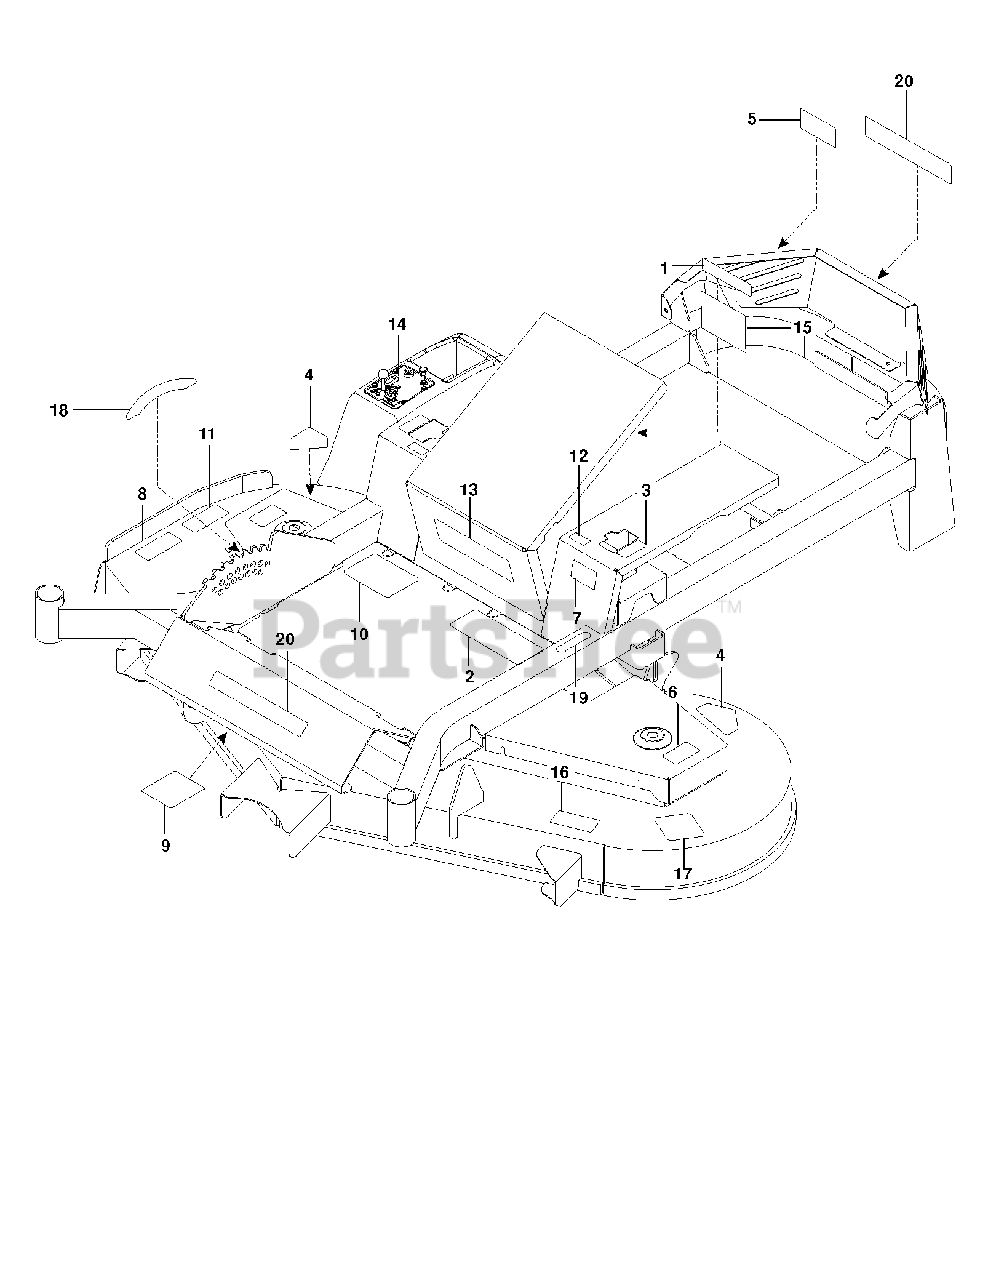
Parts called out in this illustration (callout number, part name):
2	DECAL, WARNING
3	DECAL, MOTION CONTROL
4	DECAL, CPSC
5	DECAL, BELT DRIVE
7	DECAL, FLAG
8	DECAL, EURO SEVERING
9	DECAL, BELT ROUTING
10	DECAL, WARNING
12	DECAL, TRACKING
13	DECAL, RAM ULTRA
15	DECAL, SERVICE
16	DECAL, TRI-FORCE
18	DECAL, HEIGHT ADJUSTMENT
19	DECAL, PARK BRAKE
